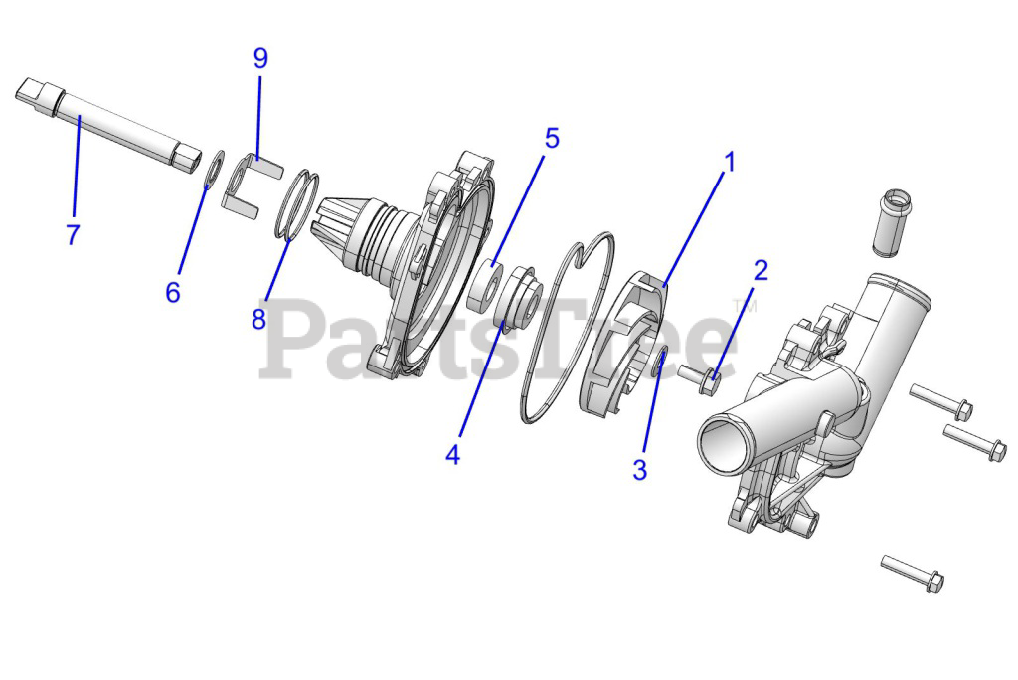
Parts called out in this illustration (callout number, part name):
1	ASM-WATER PUMP
1	IMPELLER, WATERPUMP
2	SCREW
3	WASHER, IMPELLER
4	SEAL, WATERPUMP SHAFT, MECHANICAL
5	SEAL, WATERPUMP SHAFT, OIL
6	WASHER, WATERPUMP, RETAINER
7	SHAFT, WATERPUMP,
8	O-RING
9	WASHER, WATERPUMP,RETAINER
